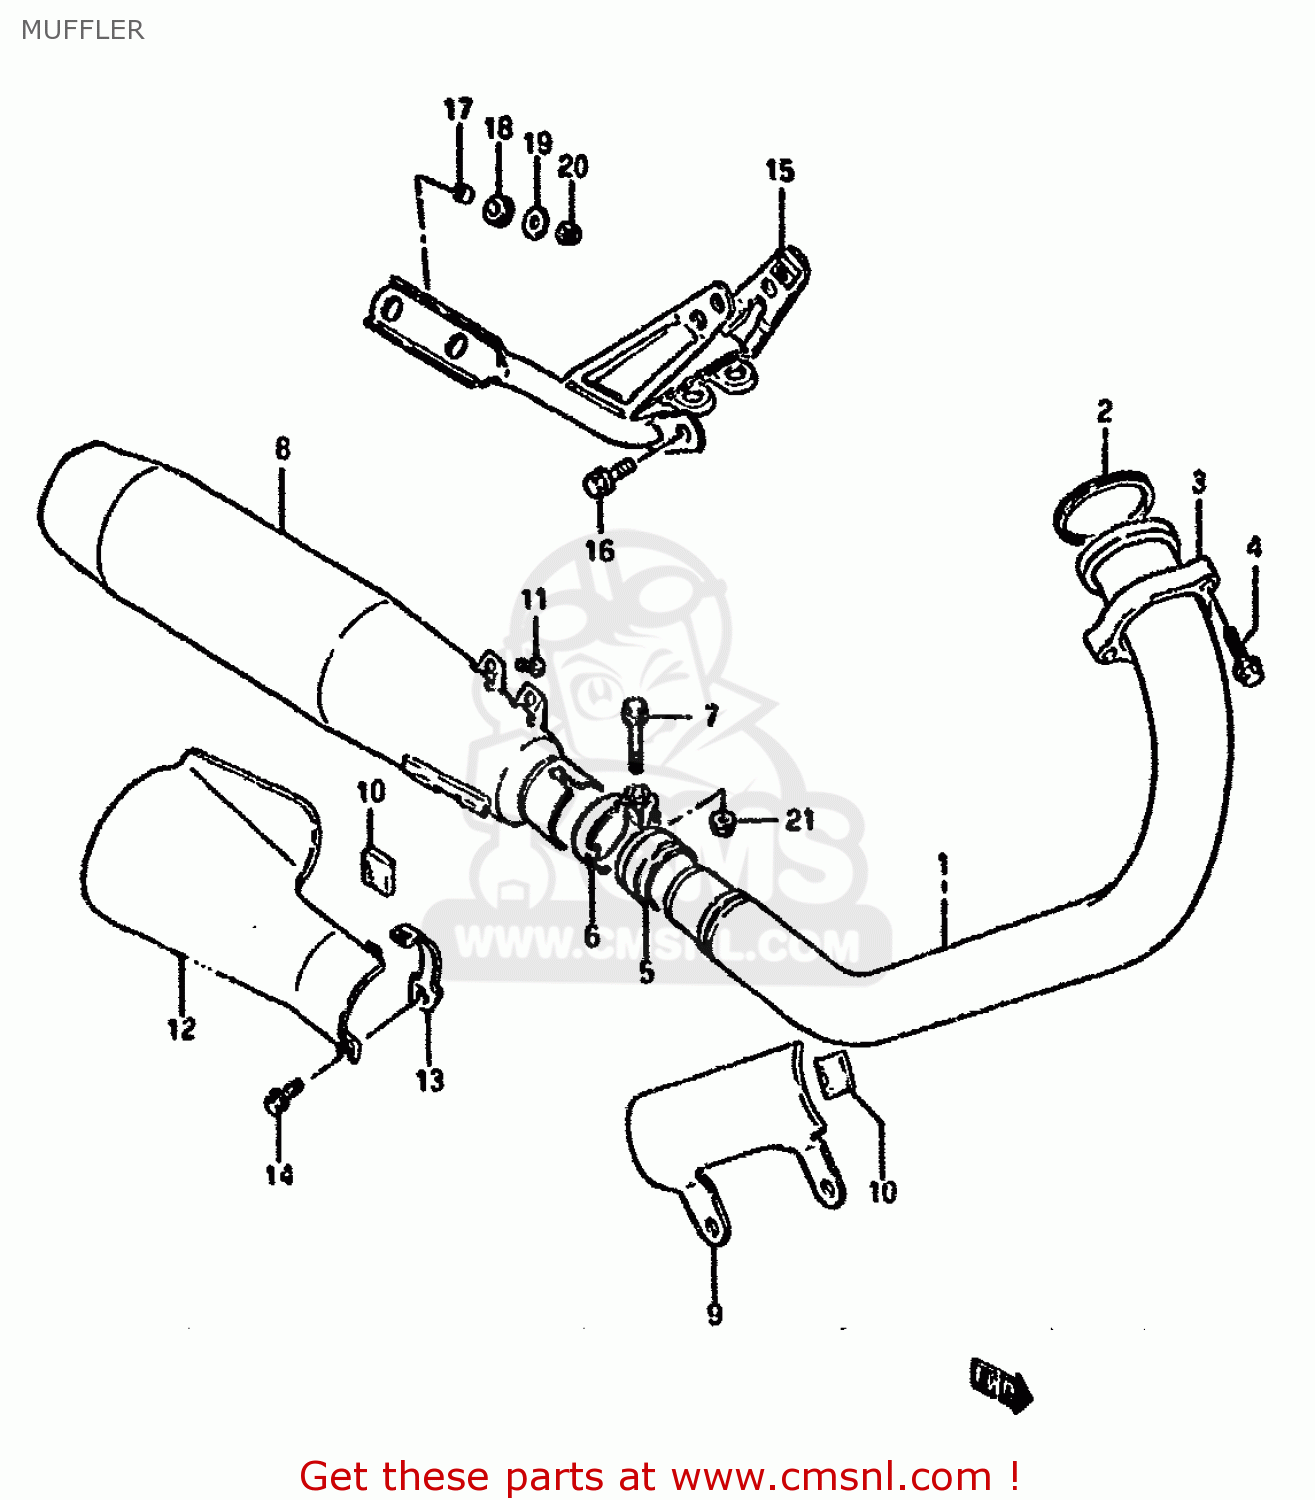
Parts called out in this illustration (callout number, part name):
1	PIPE,EXHAUST
2	GASKET,EXHAUST PIPE (NAS)
3	CLAMP,EXHAUST PIPE
4	BOLT(8X35)
5	CONNECTOR,MUFFLER
6	CLAMP,MUFFLER CONNECTOR
7	BOLT
8	BODY,MUFFLER
9	COVER,EXHAUST PIPE
10	GASKET (NAS)
11	SCREW
12	COVER,MUFFLER
13	CLAMP,MUFFLER COVER
14	BOLT
15	STAY,MUFFLER SUPPORT
16	BOLT
17	SPACER (8.8X12X11)
18	CUSHION
19	WASHER
20	NUT
21	NUT
